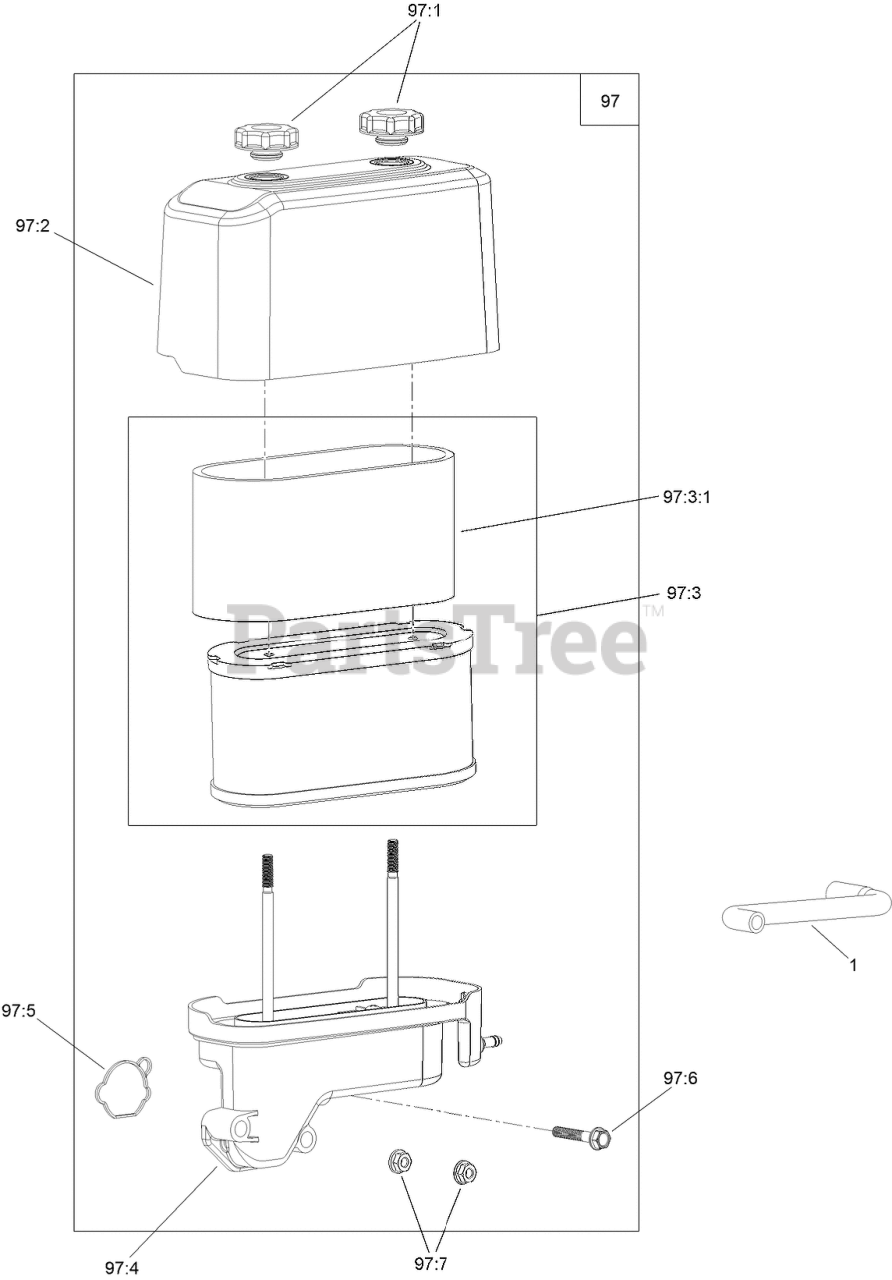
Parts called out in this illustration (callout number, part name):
1	TUBE-BREATHER
97	AIR FILTER ASM
97:1	NUT-SPEED
97:2	COVER-FILTER, AIR
97:3	AIR FILTER KIT
97:3:1	PREFILTER
97:5	GASKET-CARBURETOR
97:6	SCREW-HHF
97:7	NUT-FLANGE
